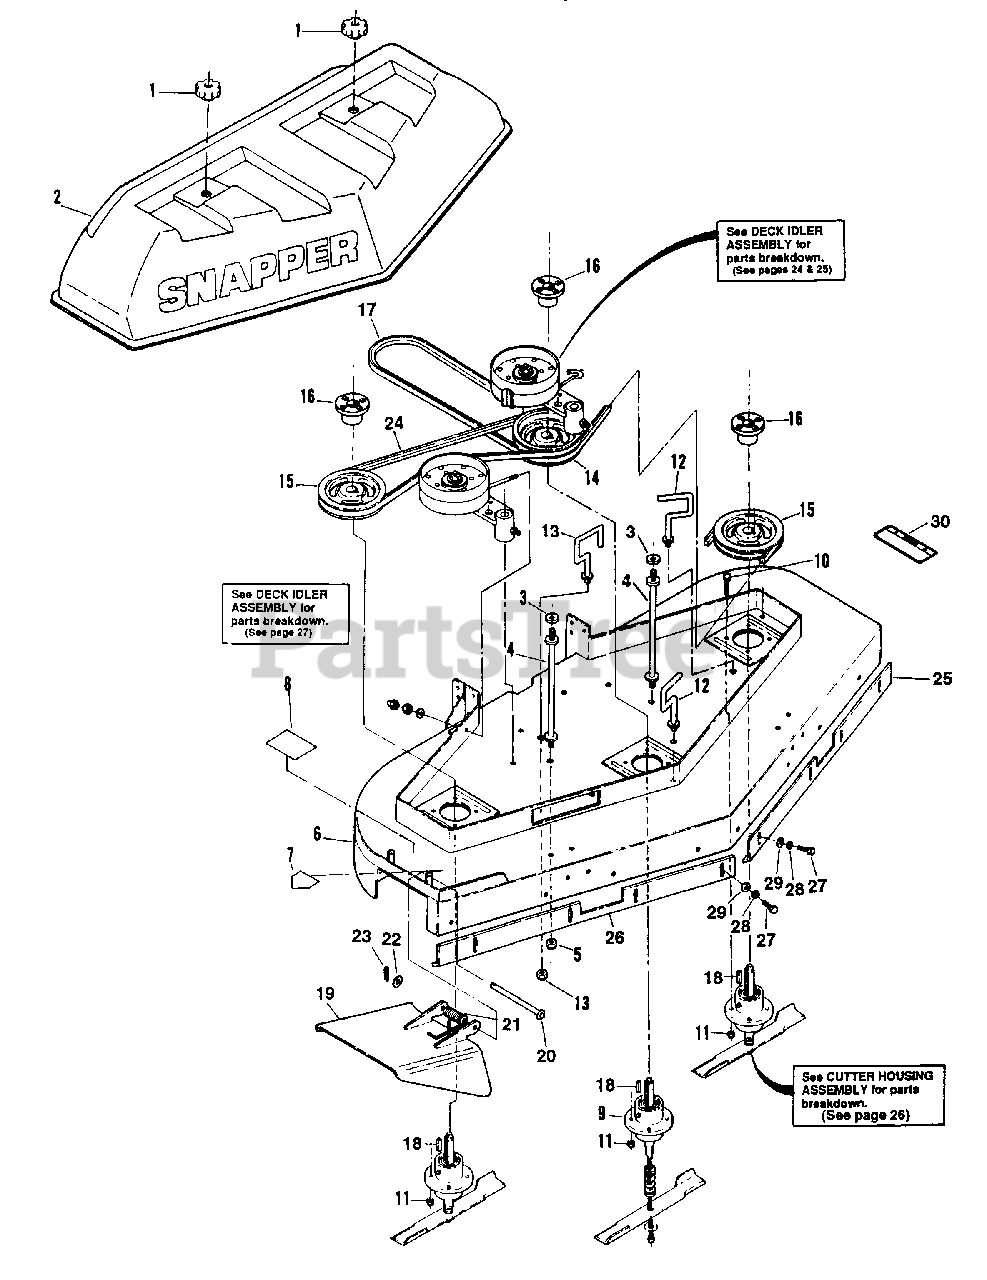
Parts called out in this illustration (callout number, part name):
1	KNOB
2	HOOD, Model PMA7480
3	BUSHING
4	STUD, Hood Mount
5	NUT, 3/8C Nyloc
6	DECK WELDMENT, 48"
7	DECAL, "Danger"
8	DECAL, "Caution"
9	ASSEMBLY, Cutter Housing
10	SCREW, 3/8-16 x 1-1/4" Hex Head Cap
11	NUT, 3/8-16 Hex Nyloc
12	GUIDE, Belt
13	GUIDE, Belt
14	PULLEY, Cutter Blade Drive (Double Groove)
15	PULLEY, Cutter Blade Drive
16	BUSHING, Taperlock
17	BELT, Engine/Deck 48"
18	KEY, Spindle
19	DEFLECTOR, 48" Chute
20	ROD, Chute Pivot
21	SPRING, Chute
22	WASHER, 5/16" Flat
23	PIN, 3/32 x 1" Cotter
24	BELT, Blade/Blade 48"
25	SKIRT, Front L.H. 48"
26	SKIRT, Front R.H. 48"
27	SCREW, 3/8C x 3/4" Grade 5 Hex Cap
28	LOCKWASHER, 3/8" Split
29	WASHER, 3/8" Flat
30	DECAL, "Caution"
